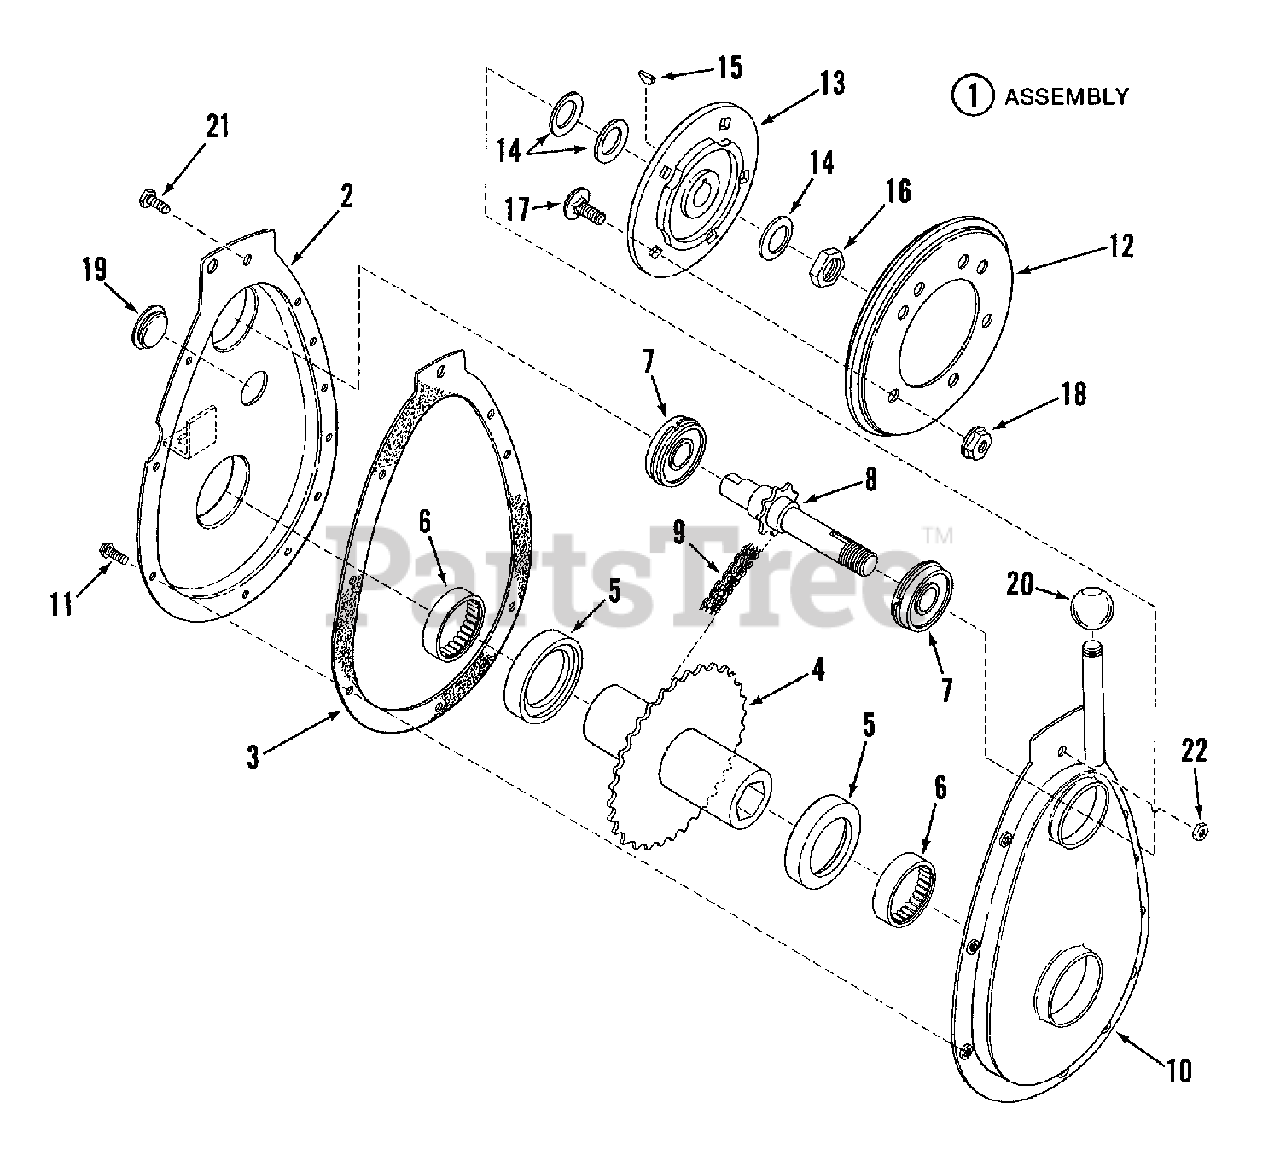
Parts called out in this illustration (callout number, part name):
1	ASSEMBLY, Primary Chain Case (NLA)
2	COVER, Case
3	GASKET, Case/Cover
4	HUB & SPROCKET
5	THRUST-WASHER
6	BEARING, Needle
7	BEARING, Ball
8	SHAFT, Input
9	CHAIN, 46 Pitch (#35)
10	CASE, Sprocket
11	SCREW, #10-24 x 1/2" Hex Washer Self-Tap (Torx)
12	DISC, Driven
13	HUB, Driven Disc
14	WASHER, Belleville
15	KEY, 1/8 x 5/8 Woodruff
16	NUT, 5/8-18 Hex Center Lock
17	CARRIAGE BOLT, 5/16-18X1/2 GR5
18	NUT, 5/8-18 Hex Flange Lock, Grade 5
19	* PLUG (Oil fill & check)
20	BUSHING, Primary Clutch Ball
21	SCREW, 1/4-20 x 5/8" Hex Head Cap, Gr. 5
22	NUT, 1/4-20 Hex Center Lock
